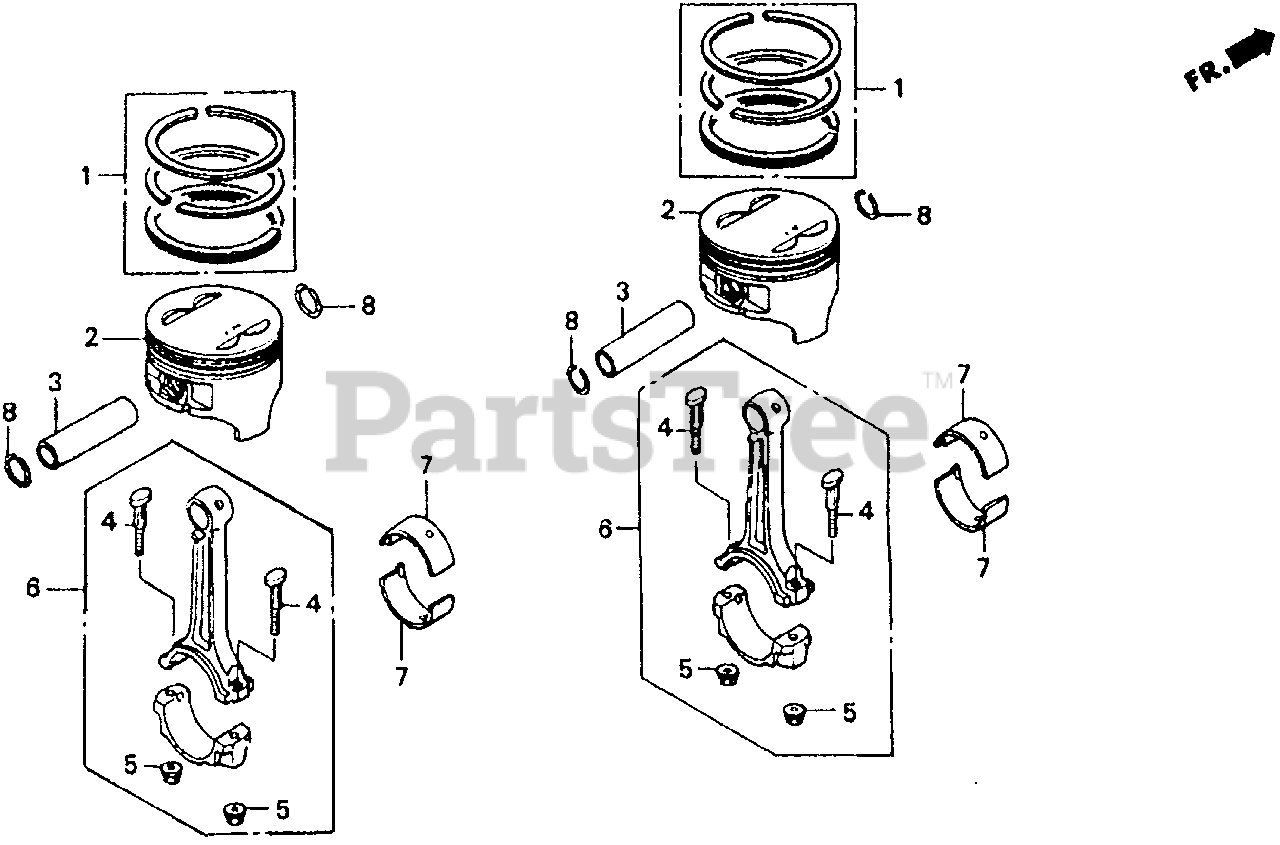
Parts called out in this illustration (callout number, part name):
1	RING SET, PISTON (STD)
1	RING SET, PISTON (OS 0.25)
1	RING SET, PISTON (OS 0.50)
2	PISTON (STD)
2	PISTON (OS 0.25)
2	PISTON (OS 0.50)
3	PIN, PISTON
4	BOLT, CONNECTING ROD (Honda Code 0837377). (TOKAI TRW)
5	NUT, CONNECTING ROD
6	ROD ASSY., CONNECTING
7	BEARING A, CONNECTING ROD (Honda Code 3505971). (BLUE)
7	BEARING B, CONNECTING ROD (Honda Code 3505989). (BLACK)
7	BEARING C, CONNECTING ROD (Honda Code 3505997). (BROWN)
7	BEARING D, CONNECTING ROD (Honda Code 3506003). (GREEN)
7	BEARING E, CONNECTING ROD (Honda Code 3506011). (YELLOW)
7	BEARING F, CONNECTING ROD (Honda Code 3506029). (PINK)
7	BEARING G, CONNECTING ROD (Honda Code 3506037). (RED)
8	CLIP, PISTON PIN (19MM)
